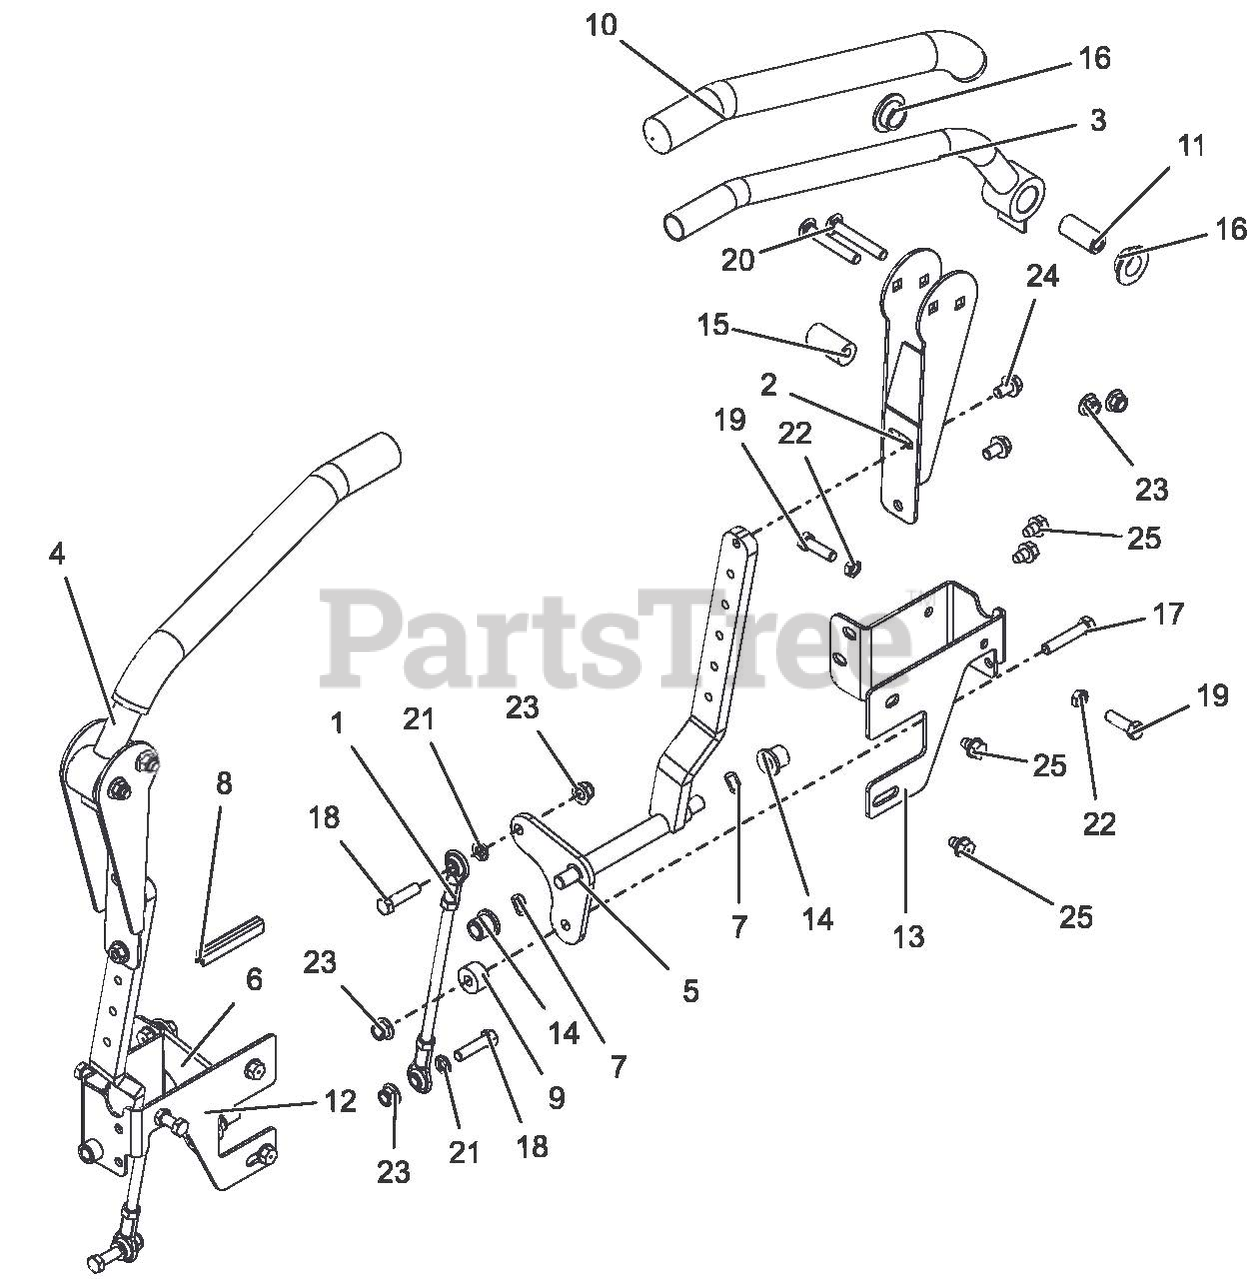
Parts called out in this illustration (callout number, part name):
1	ASM, STEERING LINKAGE
2	WLDMT, UPPER ADJUSTABLE CONTROL ARM
3	WLDMT, LH CONTROL HANDLE
4	WLDMT, RH CONTROL HANDLE
5	WLDMT, LH LOWER CONTROL ARM
6	WLDMT, RH LOWER CONTROL ARM
7	WAVE WASHER .531 X .781 X .125 FH
8	STRIP, COWL - 1.50 LG
9	SPACER .390 X 1.000 X .562
10	GRIP, HANDLEBAR
11	SPCR, STEERING ARM
12	BRKT, RH HD STEERING STOP
13	BRKT, LH HD STEERING STOP
14	BSHG-FLG .500 X .750 X .750 X .125
15	BSHG, ECCENTRIC .328 X .750 X 1.625
16	BSHG, FLANGE .762 X 1.48 X .44 NYLON
17	BLT-HEX .38-16 X 2.00 FTH GR5 YWZC
18	BLT-HEX .38-16 X 1.50 GR5 YWZC
19	BLT-HEX .38-16 X 1.25 GR5 YWZC
20	BLT-RHDSSQNK .38-16 X 2.50 G5YZ
21	WSHR-LK .38 X .094 REG YWZC
22	NUT, JAM .375-16 YWZC
23	NUT-LK-NYL-FLG .38-16 YWZC
24	BLT-SERHFWH .38-16 X .62 YWZC
25	SCR-TAP .38-16 X .50 HWH TR TWZ
